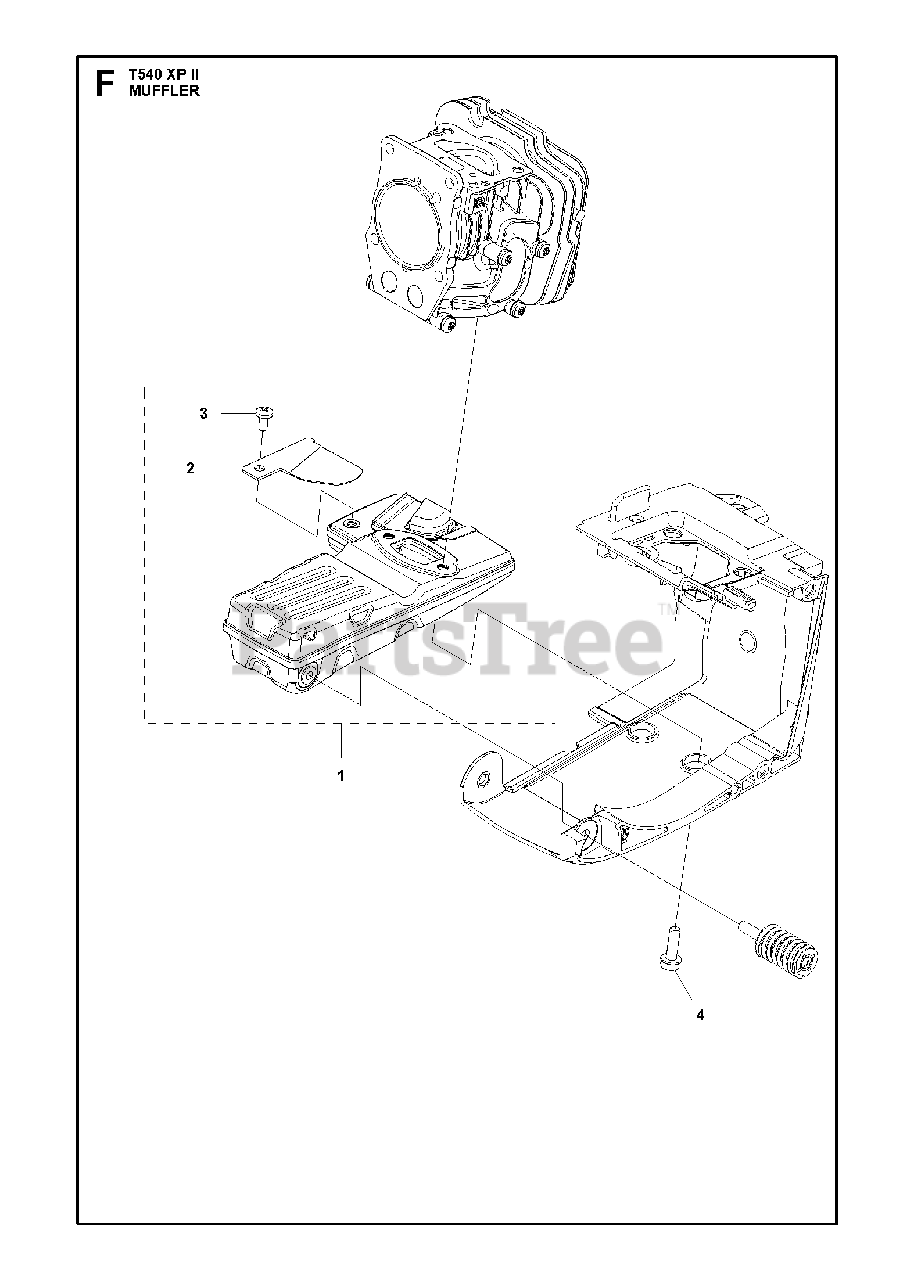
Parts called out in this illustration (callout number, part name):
1	MUFFLER ASSY
2	SPARK ARRESTOR SCREEN
3	SCREW
4	SCREW ITXSCFM
